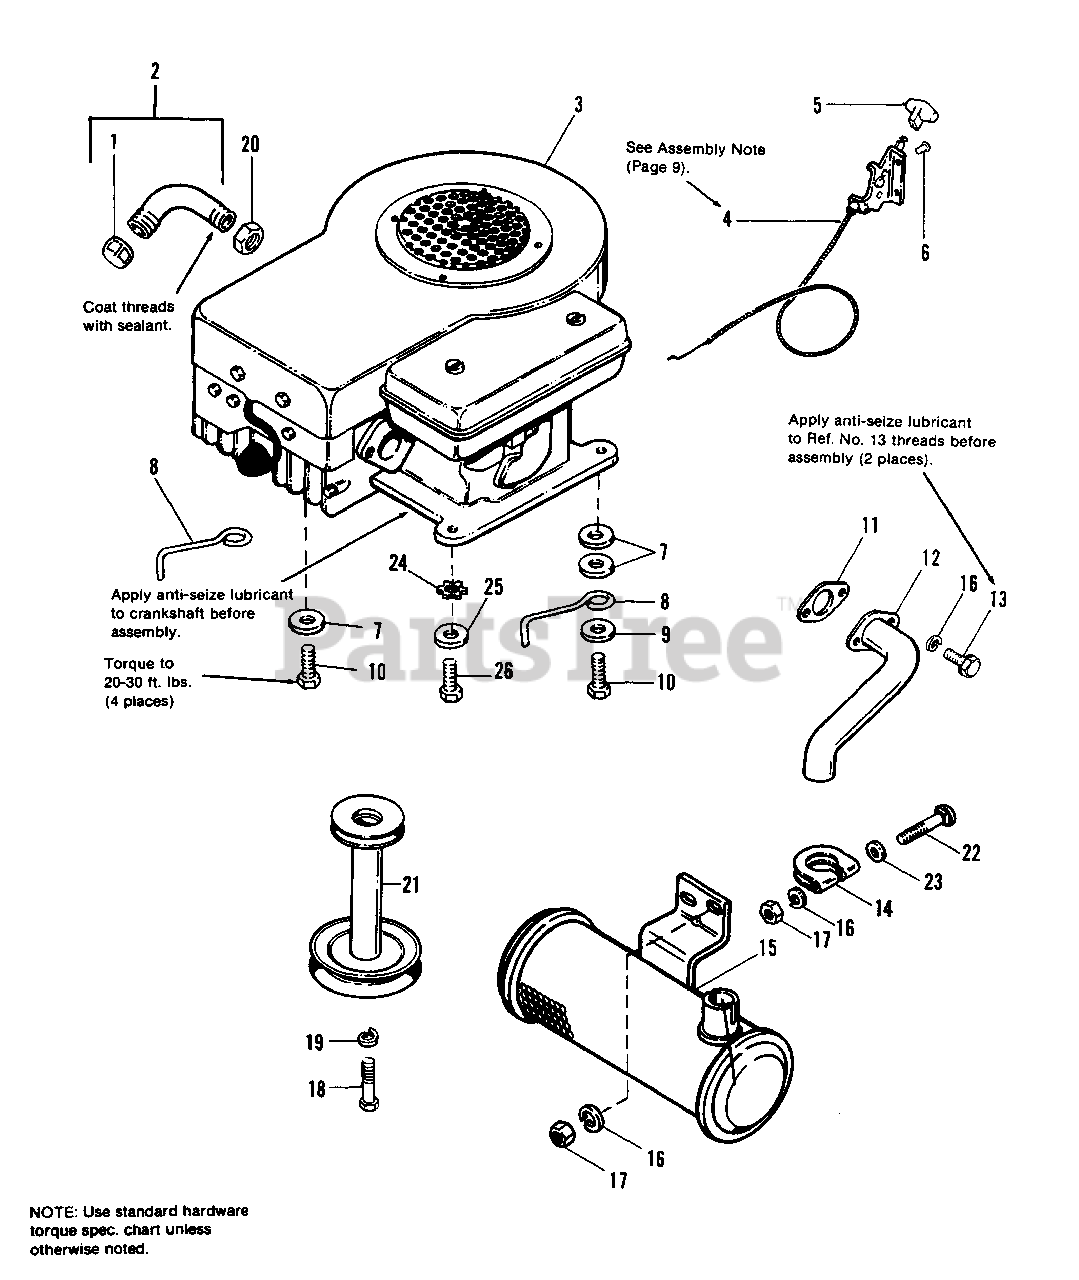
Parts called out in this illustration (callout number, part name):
1	PIPE, Cap, Hex
2	PIPE, Oil Drain (Incl. Ref. No. 1)
3	ENGINE ASSY., 11 HP
4	THROTTLE CONTROL ASSY.
5	KNOB, Throttle
6	RIVET, Pop, 1/4 x .44
7	WASHER, Plain, 13/32
8	STOP, Belt Engine
9	WASHER, Plain, 3/8
10	SCREW, Taptite, 3/8-16 x 1-1/2
11	GASKET, Muffler
12	PIPE, Exhaust
13	CAPSCREW, Hex, 5/16-18 x 3/4
14	CLAMP, Exhaust
16	LOCKWASHER, 5/16
17	NUT, Hex, 5/16-18
18	CAPSCREW, 7/16-20 x 1-1/4
19	LOCKWASHER, 7/16
20	LOCKNUT, Conduit, 3/8
21	PULLEY ASSY., Engine
22	BOLT, Carriage, 5/16-18 x 2-3/4
23	WASHER, 5/16
24	LOCKWASHER, Ext. Tooth, (Zinc Pltd.)
25	WASHER (Zinc Pltd.)
26	SCREW, Taptite, 3/8-16 x 1-1/2 (Zinc Pltd.)
